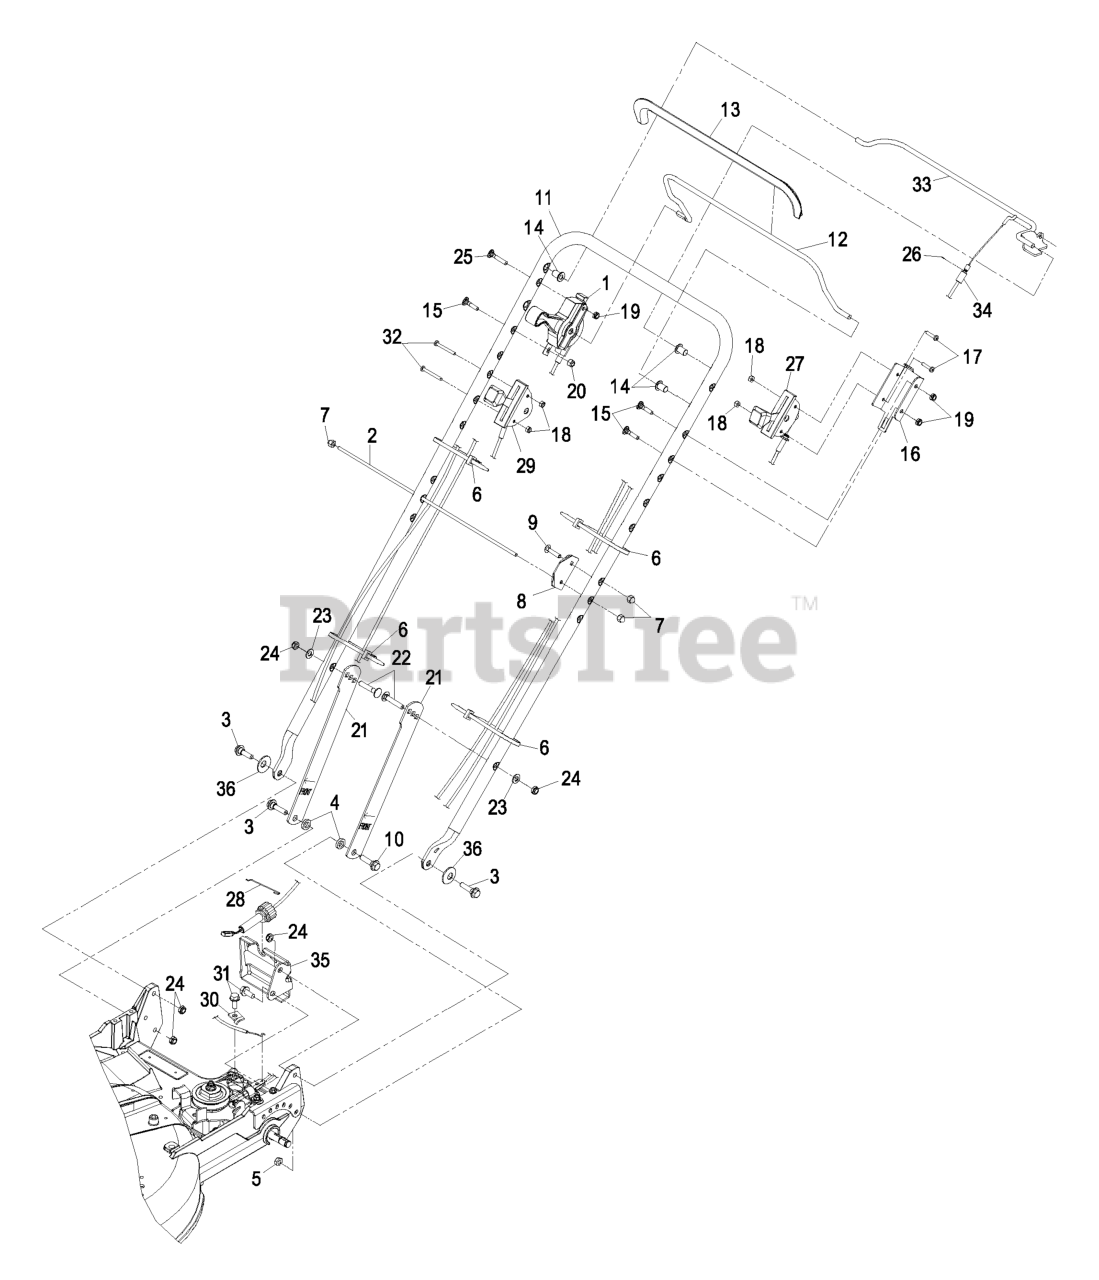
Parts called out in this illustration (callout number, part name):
1	CONTROL,BBC
2	ROD,BAG SUPPORT
3	SCREW-SHOULDER
4	SPACER
5	NUT-LOCK, NI
6	TIE-CABLE
7	NUT-CAP
9	SCREW-CARR
10	SCREW-SHOULDER
12	BAIL,BRAKE BBC
13	PAD,DEADMAN
14	BUSHING
15	SCREW-HANDLE
16	BRACKET,THROTTLE
17	SCREW-PPH
18	NUT-LOCK, NI
19	NUT-LOCK, NI
20	NUT-LOCK, NI
22	BOLT-CARR
23	WASHER-PLAIN
24	NUT-LOCK, NI
27	CABLE,THROTTLE KAWASAKI
28	RETAINER-CABLE
29	CABLE,SHIFTER
30	CLAMP-CABLE
31	Screw-HWH 5/16-18 X 3/4 Tf
32	SCREW-PPH
33	WLD,BAIL TRACTION (PLATED
34	CABLE,TRACTION
35	BRACKET-ADJUSTMENT, TRACT
36	WASHER-SPRING
